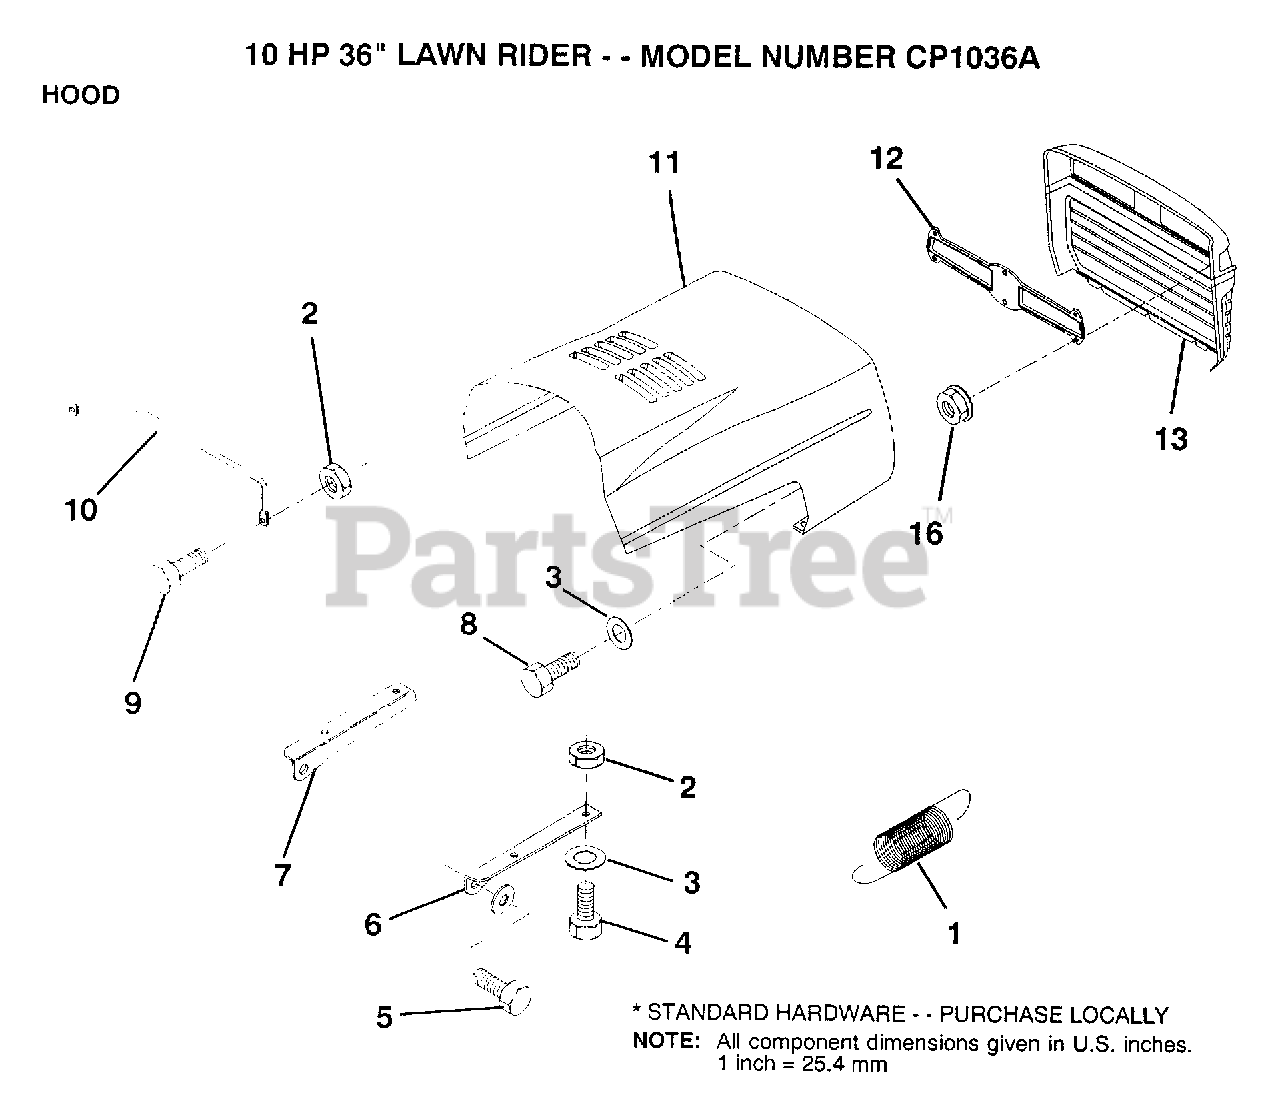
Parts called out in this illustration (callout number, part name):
1	EXT SPRING
2	NUT
3	WASHER
4	BOLT
6	BRKT HOOD RH
7	BRKT HOOD LH
10	"BRACE,HOOD"
16	NUT
18	WASHER
